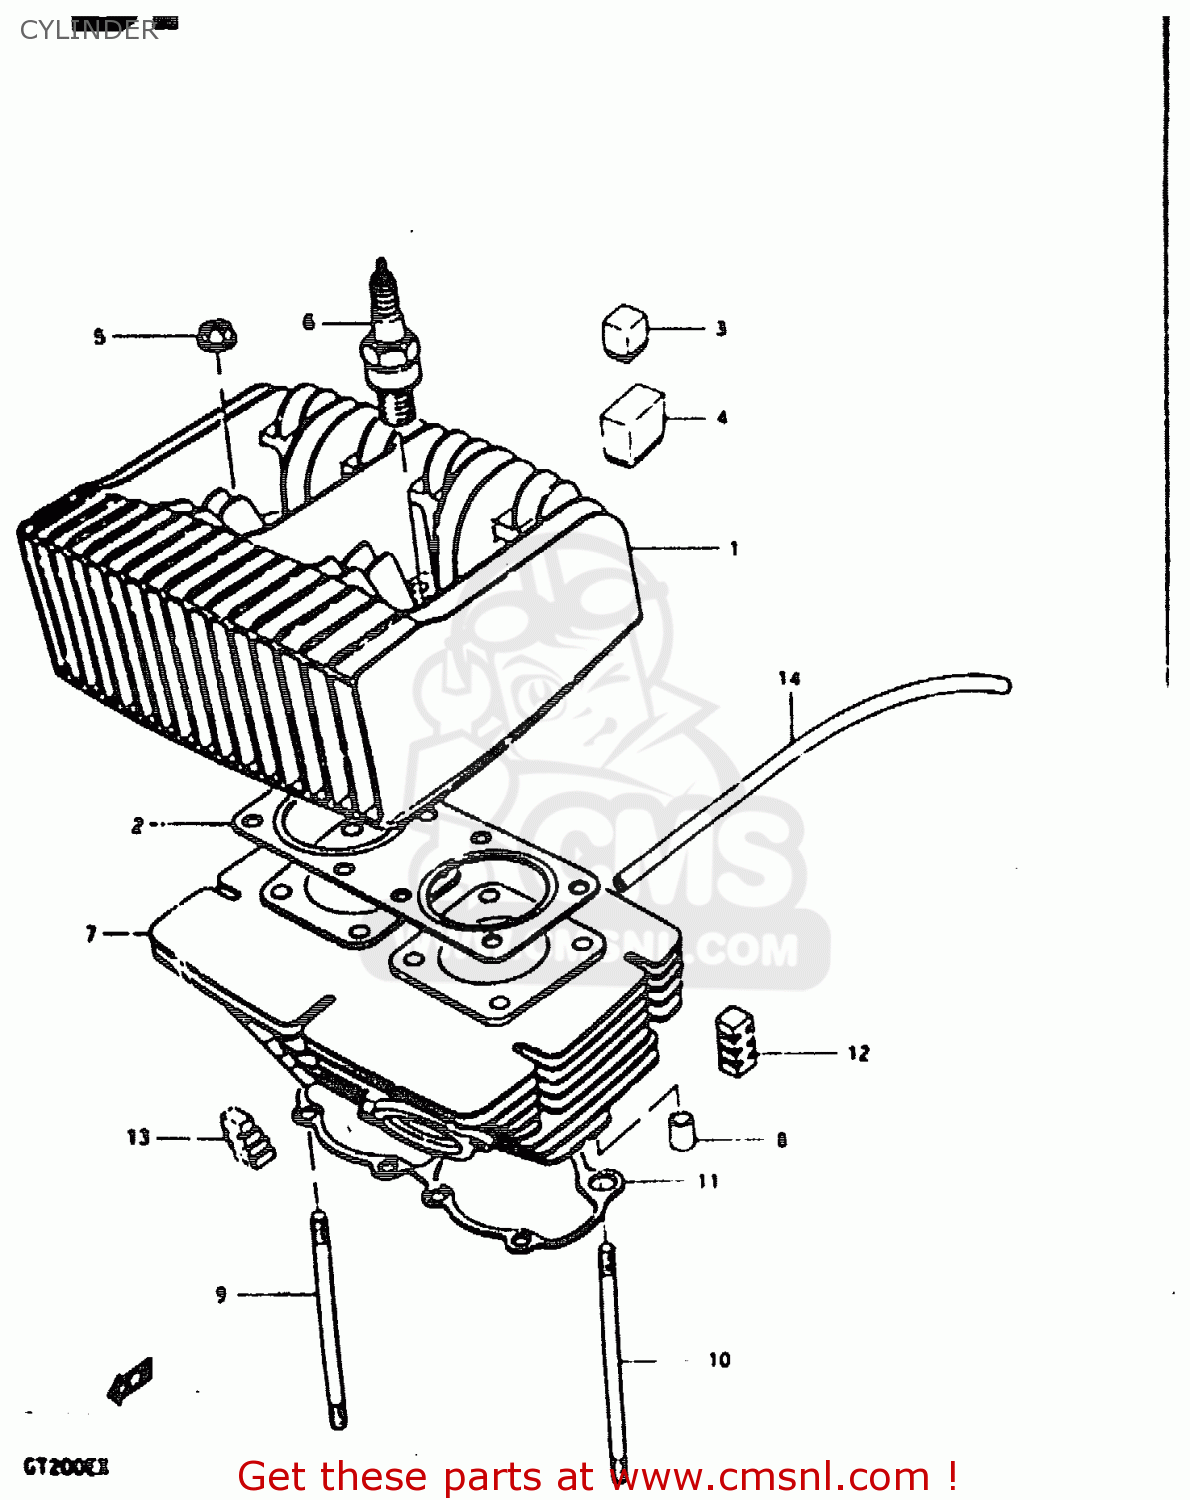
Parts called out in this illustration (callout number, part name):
1	CYLINDER HEAD
2	GASKET,CYLINDER HEAD (NAS)
3	PAD
4	PAD,CYLINDER
5	NUT
6	PLUG,SPARK
7	CYLINDER
8	PIN
9	BOLT,STUD
10	BOLT,STUD
11	GASKET, CYLINDER (MCA)
12	PAD,CYLINDER
13	RUBBER PAD, CYLINDER FRONT
14	HOSE
